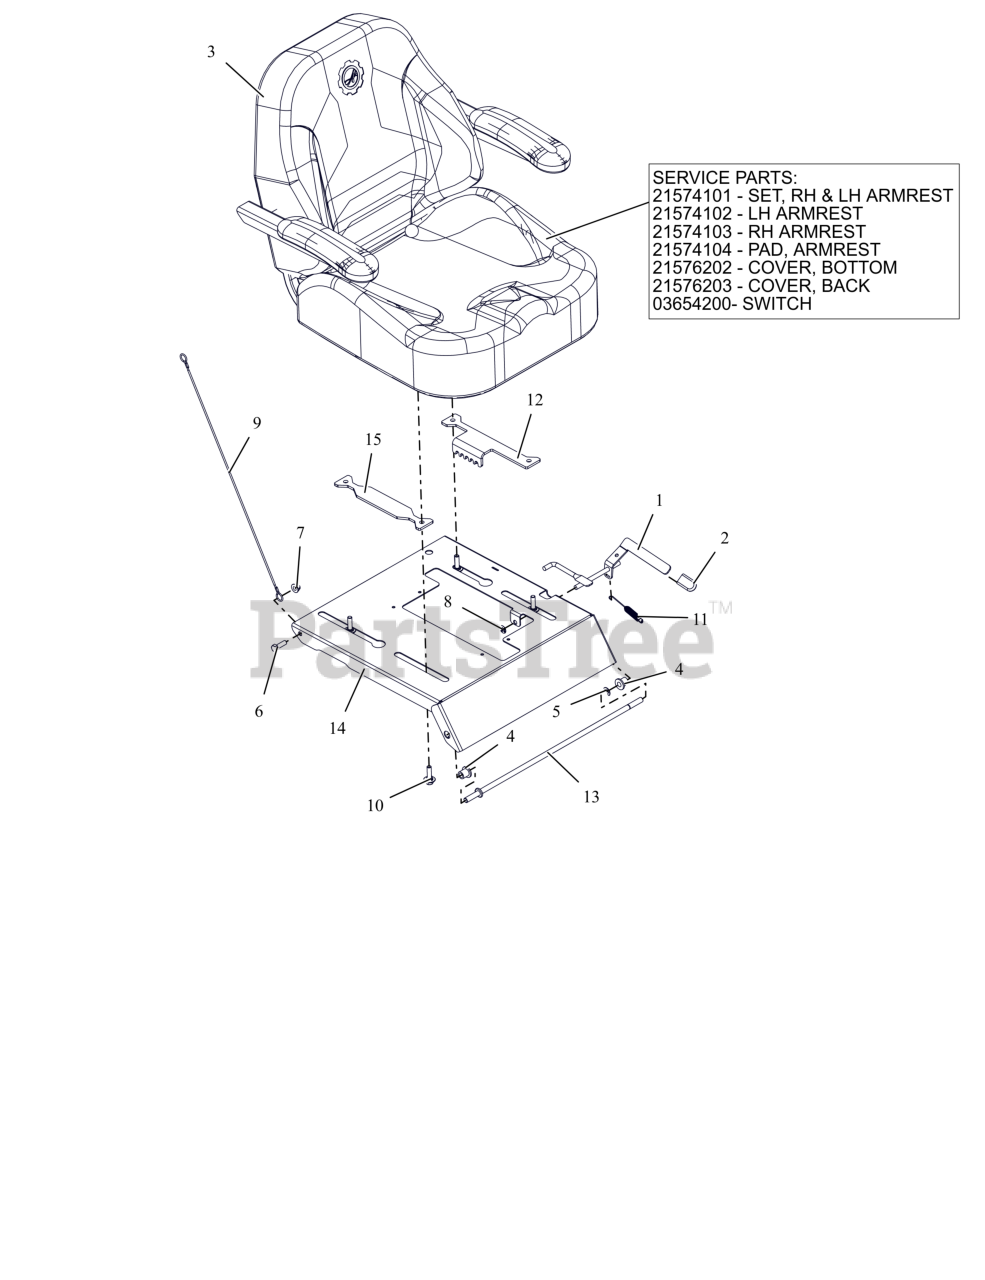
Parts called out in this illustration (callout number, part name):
1	WLDMT, ADJUSTABLE SEAT LATCH
2	GRIP, SEAT LEVER, GREY
3	SEAT- IKON XD
3	SET, RH & LH ARMREST
3	LH ARMREST
3	RH ARMREST
3	PAD, ARMREST
3	COVER, BOTTOM
3	COVER, BACK
3	SWITCH- SEAT
4	BSHG-FLG .38X.580X.667X.750
5	RG-RTNG-EXT .375X.035 TYP E
6	BLT,HEX .31-18X1.00 G5 ZCC
7	NUT,LK-NYL-FLG .31-18 G5ZC120
8	NUT-PUSH .312
9	LANYARD, SEAT CABLE .093X19.5
10	BLT, SHLDR .31-18 X .100
11	SG-TENS .043X.44X3.31 WLD 5.8
12	PLATE, ADJUSTABLE SEAT TRACK (BLACK)
13	ROD- SEAT PIVOT
14	PLATE, SEAT (ORANGE)
15	PLATE, ADJUSTABLE SEAT TRACK (BLACK)
